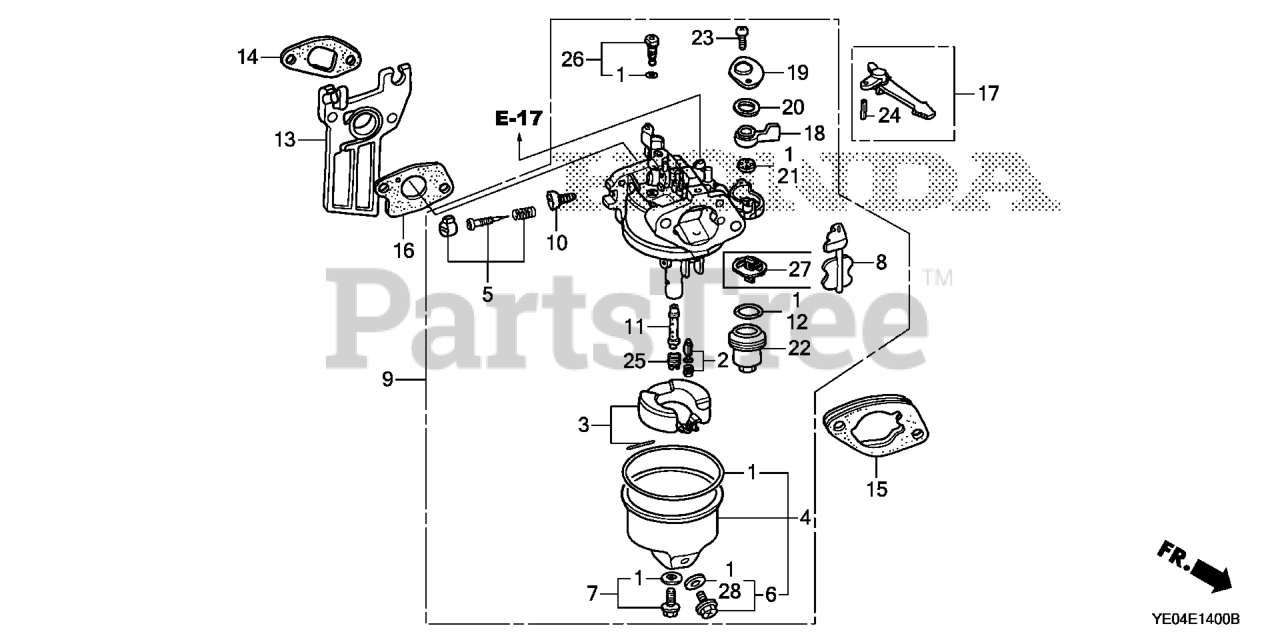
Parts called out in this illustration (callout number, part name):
1	GASKET SET
2	VALVE SET, FLOAT (CARBURETOR NO.) (SEAT NOT INCLUDED)
3	FLOAT SET
4	CHAMBER SET, FLOAT
6	SCREW SET, DRAIN
7	SCREW SET (CARBURETOR NO.)
8	CHOKE SET
9	CARBURETOR ASSY. (BE99M A)
10	SCREW, THROTTLE STOP
11	NOZZLE, MAIN (CARBURETOR NO.)
12	GASKET, FUEL STRAINER CUP
13	INSULATOR, CARBURETOR
14	GASKET, INSULATOR
15	SPACER, CARBURETOR
16	GASKET, CARBURETOR
17	LEVER, CHOKE (STD)
18	LEVER, VALVE
19	PLATE, LEVER SETTING (CARBURETOR NO.)
20	SPRING, PETCOCK LEVER (CARBURETOR NO.)
21	GASKET, VALVE
22	CUP, FUEL STRAINER
23	SCREW, PAN (3X6)
24	PIN, SPRING (2X12)
25	JET, MAIN (#65)
25	JET, MAIN (#60)
25	JET, MAIN (#62)
26	JET SET, PILOT (#40) (ADVENTURE GREEN) (CARBURETOR NO.)
27	FILTER, CUP (CARBURETOR NO.)
28	WASHER, PLAIN (6.2X10.7 DRAIN) (CARBURETOR NO.)
